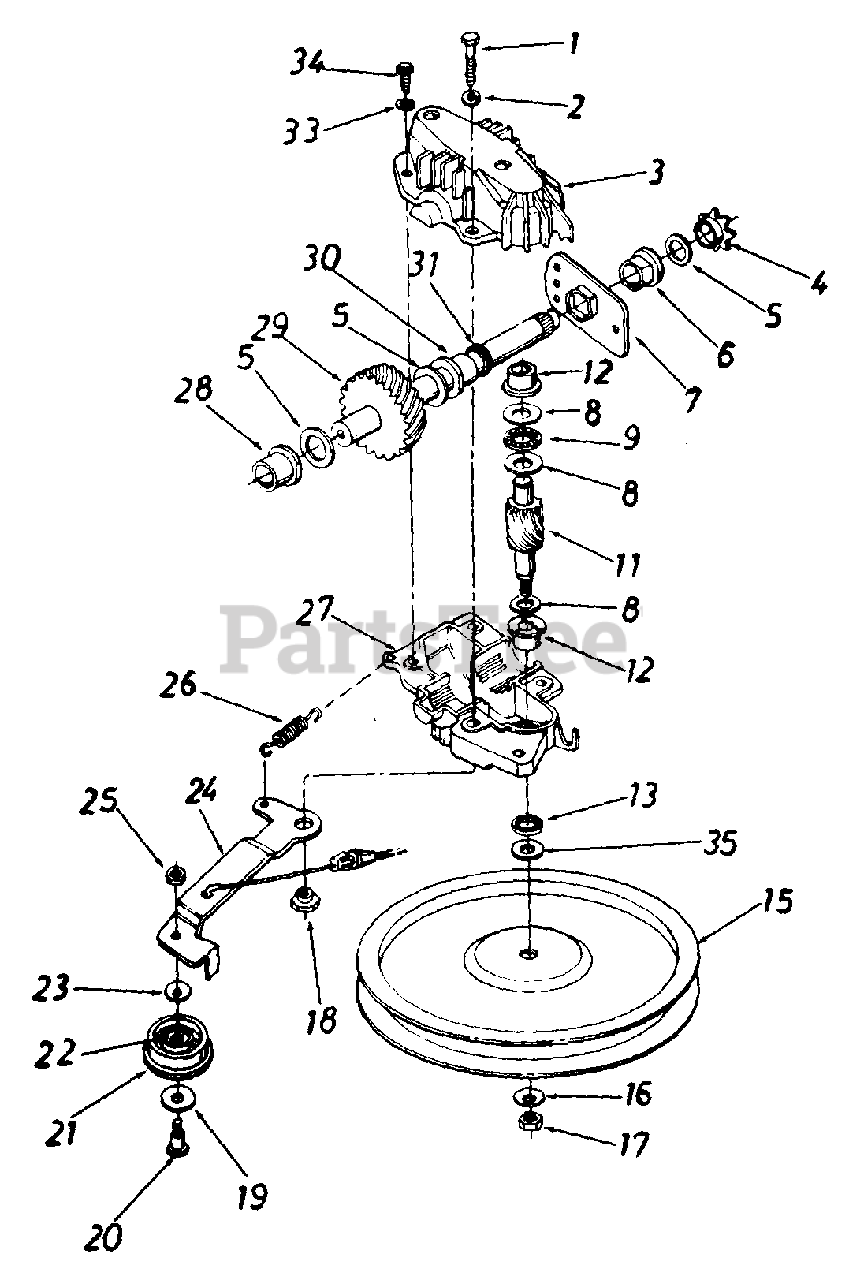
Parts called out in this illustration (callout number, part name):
1	Hex Bolt 1/4-20 x 1.25" Lg. w/Patch
2	L-Wash. 1/4" I.D.
3	Upper Hsg. Half
4	#48 Sprocket 7 Tooth x 1/2 Pitch
5	Fl-Wash. 5/8" I.D. x .030
6	Hex Flange Brg..631" I.D.
8	Thrust Wash. .382" I.D. x .70" O.D.
9	Thrust Bearing .375" I.D. x .812" O.D.
11	11 Tooth Pinion Shaft
12	Flange Bearing
15	Fl-Pulley 5.06" O.D.
16	Bell-Wash. .265" I.D. x .75"
17	Hex L-Nut 1/4-28 L.H. Thd.
18	Shld. Spacer .375" Dia. x .170
19	Fl-Wash. .390" I.D. x 1.0"
20	Shld. Bolt .375" Dia. x .40"
21	Fl-Idler Plastic 1.50" Dia.
22	Needle Brg. .375" x .31
23	Bell-Wash. .265" I.D. x .75"
24	Idler Brk't. Ass'y.
25	Hex Patch L-Nut 1/4-28 Thd.
26	Extension Spring 1.12" Lg.
27	Lower Hsg. Half
28	Flange Bearing .566 Dia.
29	Shaft Ass'y. w/Gear
30	Flange Bearing .629 Dia.
31	Oil Seal .625 Dia.
33	L-Wash. #10 I.D.
34	Hex B-Tap Scr. #10 x .62"
35	Hex Washer .26" x .88"
